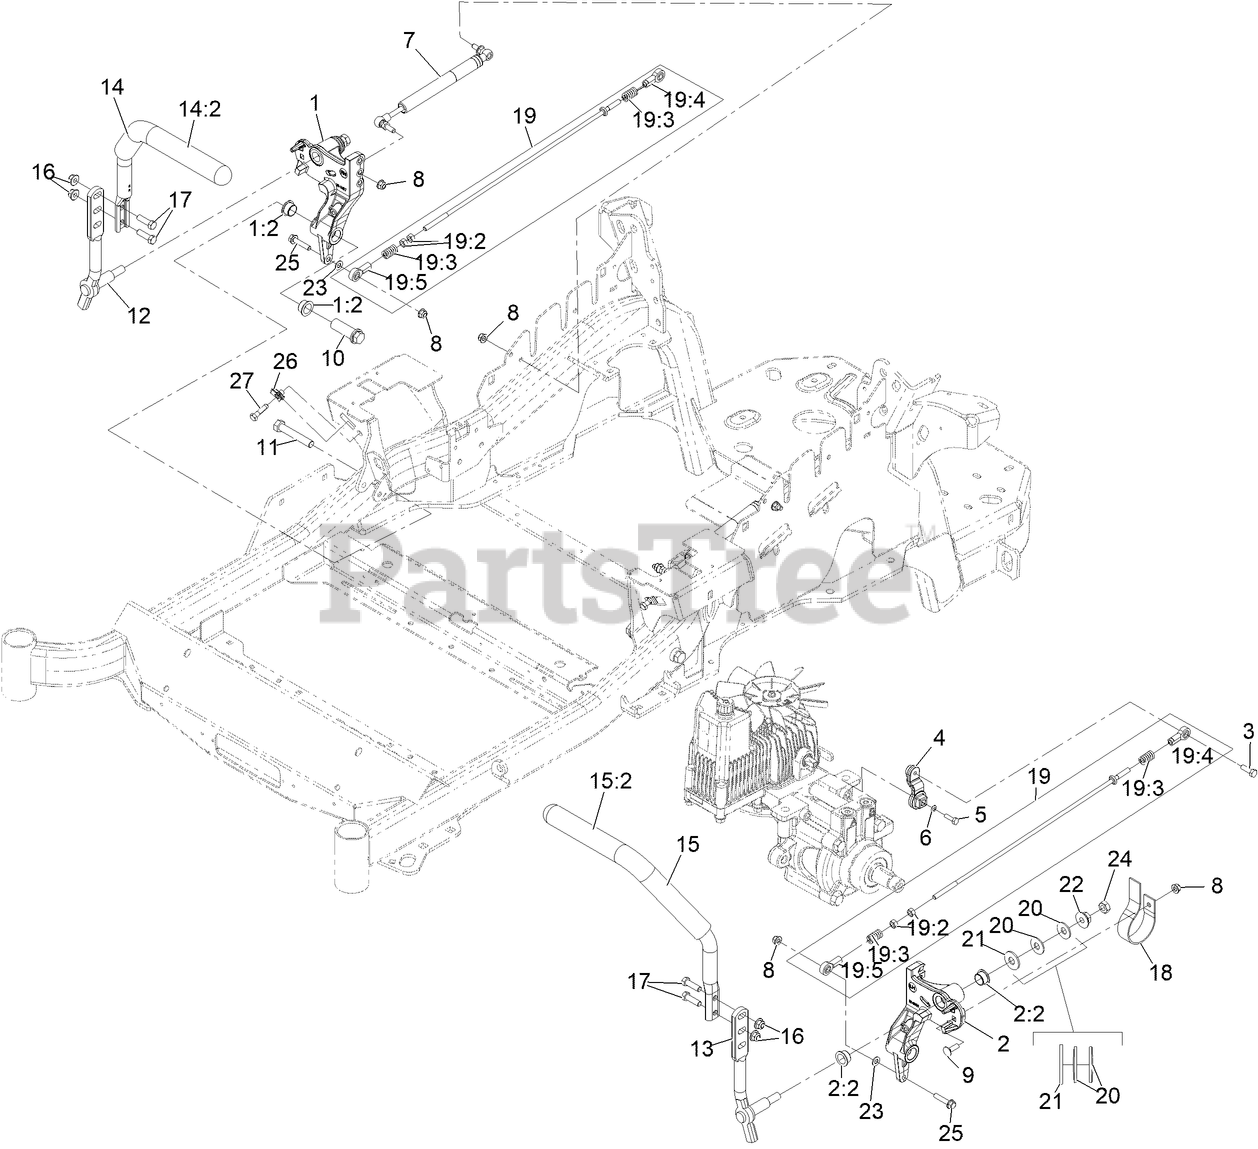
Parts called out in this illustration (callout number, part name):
1	RH MOTION CONTROL AND BUSHING ASM
1:2	BUSHING-FLANGE
2	LH MOTION CONTROL AND BUSHING ASM
2:2	BUSHING-FLANGE
3	SCREW-HH, THREAD LOCKING
4	ARM-CONTROL, PUMP
5	SCREW-HH
6	WASHER-SPRING
7	DAMPER-CONTROL, MOTION
8	NUT-HF, NI
9	BOLT-CARR
10	HUB-THREADED
11	SCREW-HH
12	LEVER-CONTROL MOTION, RH
13	LEVER-CONTROL MOTION, LH
14	RH HANDLE ASM
14:2	GRIP-LEVER, CONTROL
15	LH HANDLE ASM
15:2	GRIP-LEVER, CONTROL
16	NUT-HF, NI
17	SCREW-HH
18	SPRING-LEAF
19	PUMP LINKAGE REAR ASM
19:2	NUT-HEX
19:3	SPRING-COMPRESSION
19:4	BALLJOINT-LH
19:5	BALLJOINT-RH
20	WASHER-SPRING
21	WASHER-FLAT
23	WASHER-PLAIN
24	NUT-JAM
25	SCREW-HHF
27	SCREW-HH,LOCK
